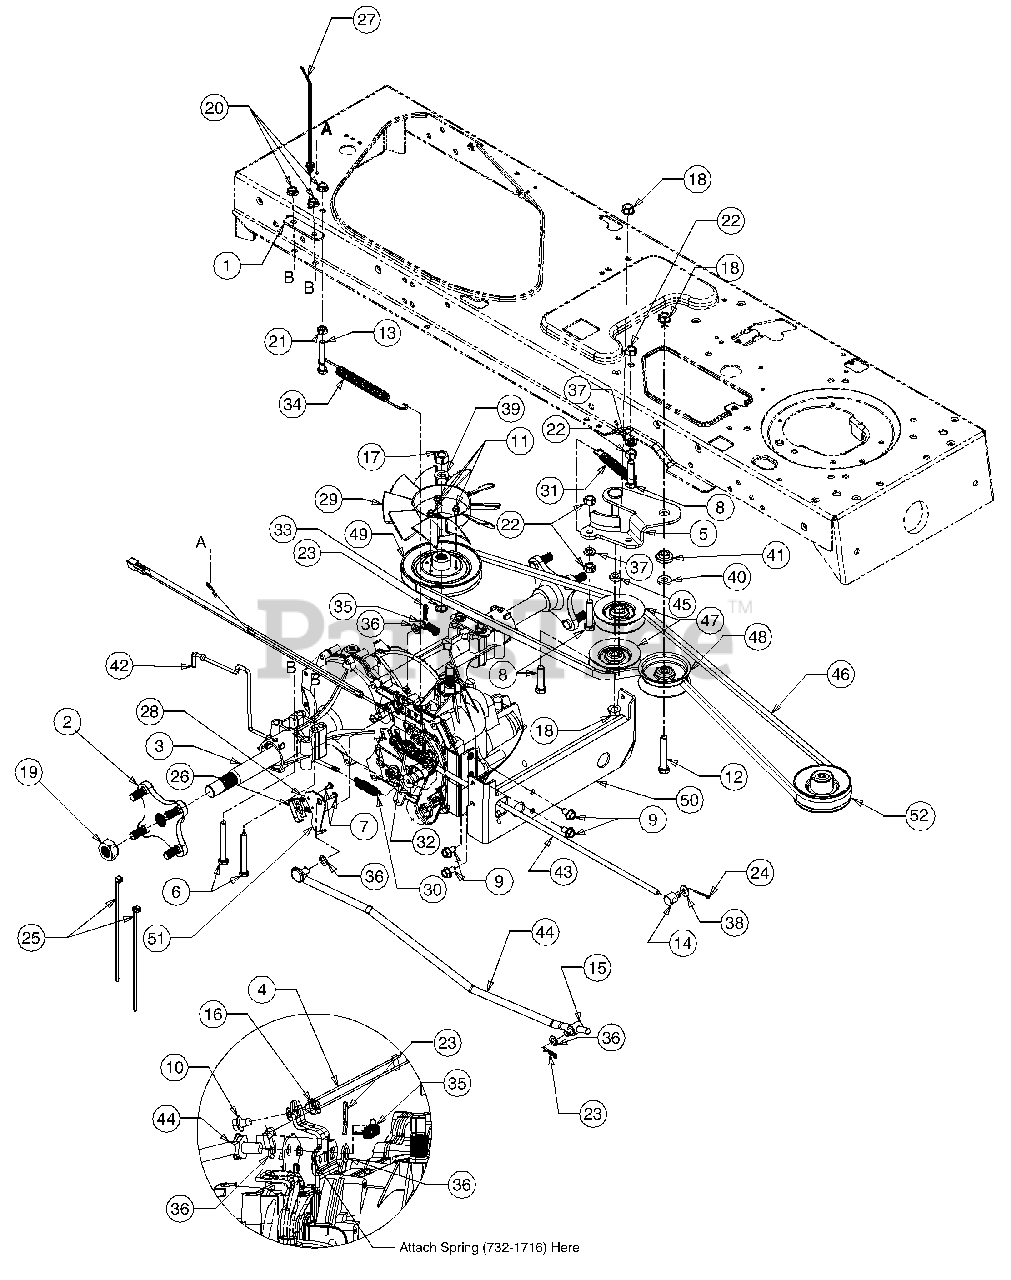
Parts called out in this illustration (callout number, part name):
2	Hub Assembly, Wheel
3	Transmission, Hydrostatic
4	Harness Assembly, Ground & Reverse
5	Bracket Assembly, Idler, Center Dbl
6	Hex Cap Screw, 5/16-18, 2.75, Gr5
7	Screw, #8-18, 0.500
8	Hex Cap Screw, 3/8-16, 1.50, Gr5
9	Screw, 5/16-18, 0.625
10	Screw, 1/4-20, 0.375
11	Screw, #12-24, 0.375
12	Hex Cap Screw, 3/8-16, 2.25, Gr5
13	Hex Cap Screw, 5/16-18, 2.00, Gr5
14	Ferrule, 5/16-18 x .312 Dia
15	Ferrule, 3/8-24 x .375 Dia
16	Nut, Hex Lock, 1/4-20
17	Nut, Hex, 1/2-20, Gr2
18	Nut, Flange Lock, 3/8-16
19	Nut, 3/4-16, Grb, Hx
20	Nut, Flange Lock, 5/16-18, Gr5
21	Nut, Hex, 5/16-18, Gr5
22	Nut, Hex, 3/8-16, Gr8
23	Pin, Cotter, .072 Dia. x 1.13 Lg
24	Pin, Cotter, 3/32, 1.0
25	Cable, Tie, 3/16 x .05 x 7.4
26	Switch, Spring, Short
27	Tie, Cable, Push Mount 7.5 Lg
28	Plate, Insulator Nut
29	Fan, Blade, 10"
30	Spring, .48 OD x 2.03 Extension
31	Spring, Extension, .50 Dia x 3.97 Lg
32	Spring, Extension, .59 OD x 4.00 Lg
33	Ring, Wire
34	Spring, Extension, .500 Dia x 7.0 Lg
35	Spring, Extension, 3/8 OD x 1.44 Lg
36	Washer, Flat, .385 x .62 x .063
37	Washer, Lock, 3/8, Regular Duty
38	Washer, Flat, .344 x .688 x .065
39	Washer, Lock, 1/2, Regular Duty
40	Washer, Flat, .407 x .812 x .135 Hdn
41	Spacer, Shoulder, 1.00 x .38 x .38
42	Rod, Hydro Bypass
43	Rod, Brake, Hydro
44	Rod, Control, Hydro
45	Spacer, .376 ID x .625 OD x .22
46	Belt, V Type, Poly
47	Pulley, Idler, V Type x 3.06 Dia
48	Pulley, Idler, Flat 2.75 OD
49	Pulley, Input, 5.0 Dia
52	Pulley, Engine, 3.56 Dia
